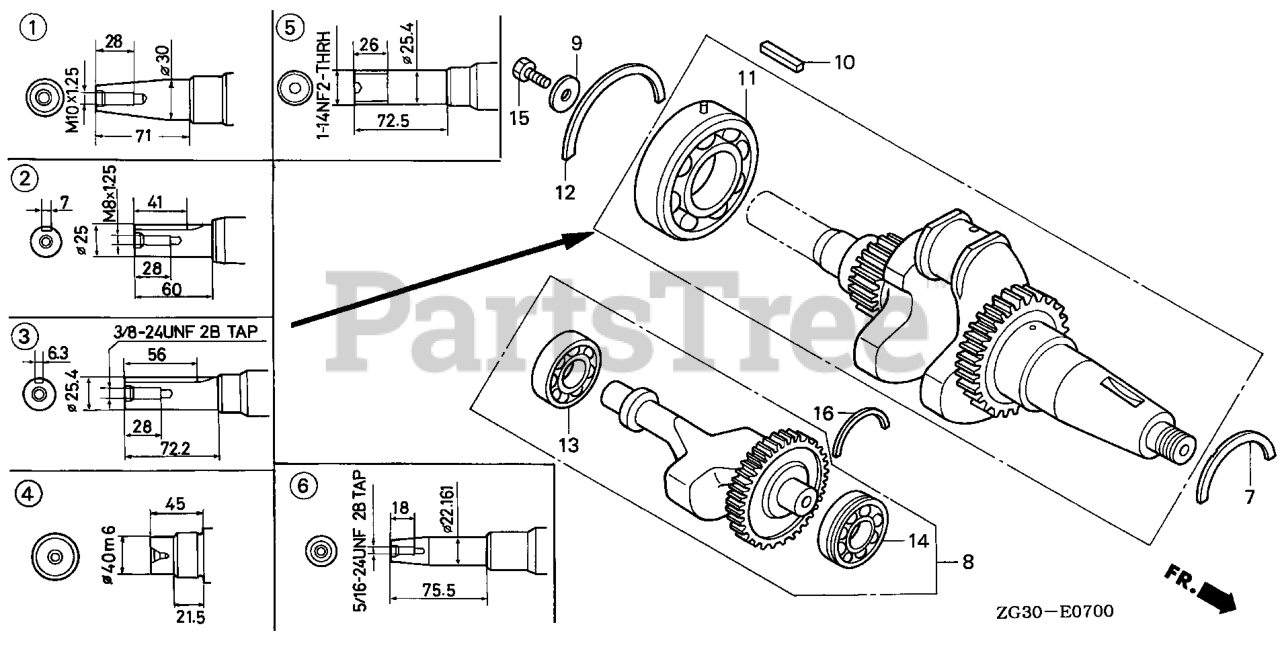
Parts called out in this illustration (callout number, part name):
3	CRANKSHAFT (Q-TYPE)
7	BEARING A, CRANKSHAFT THRUST (BLUE)
8	WEIGHT, BALANCER
10	KEY (6.3X6.3X43)
11	BEARING, SPECIAL (6308) (NTN CORP.)
12	SET-RING (90)
13	BEARING B, SPECIAL BALL (6304)
14	BEARING C, SPECIAL BALL (6304)
16	SET-RING (520)
